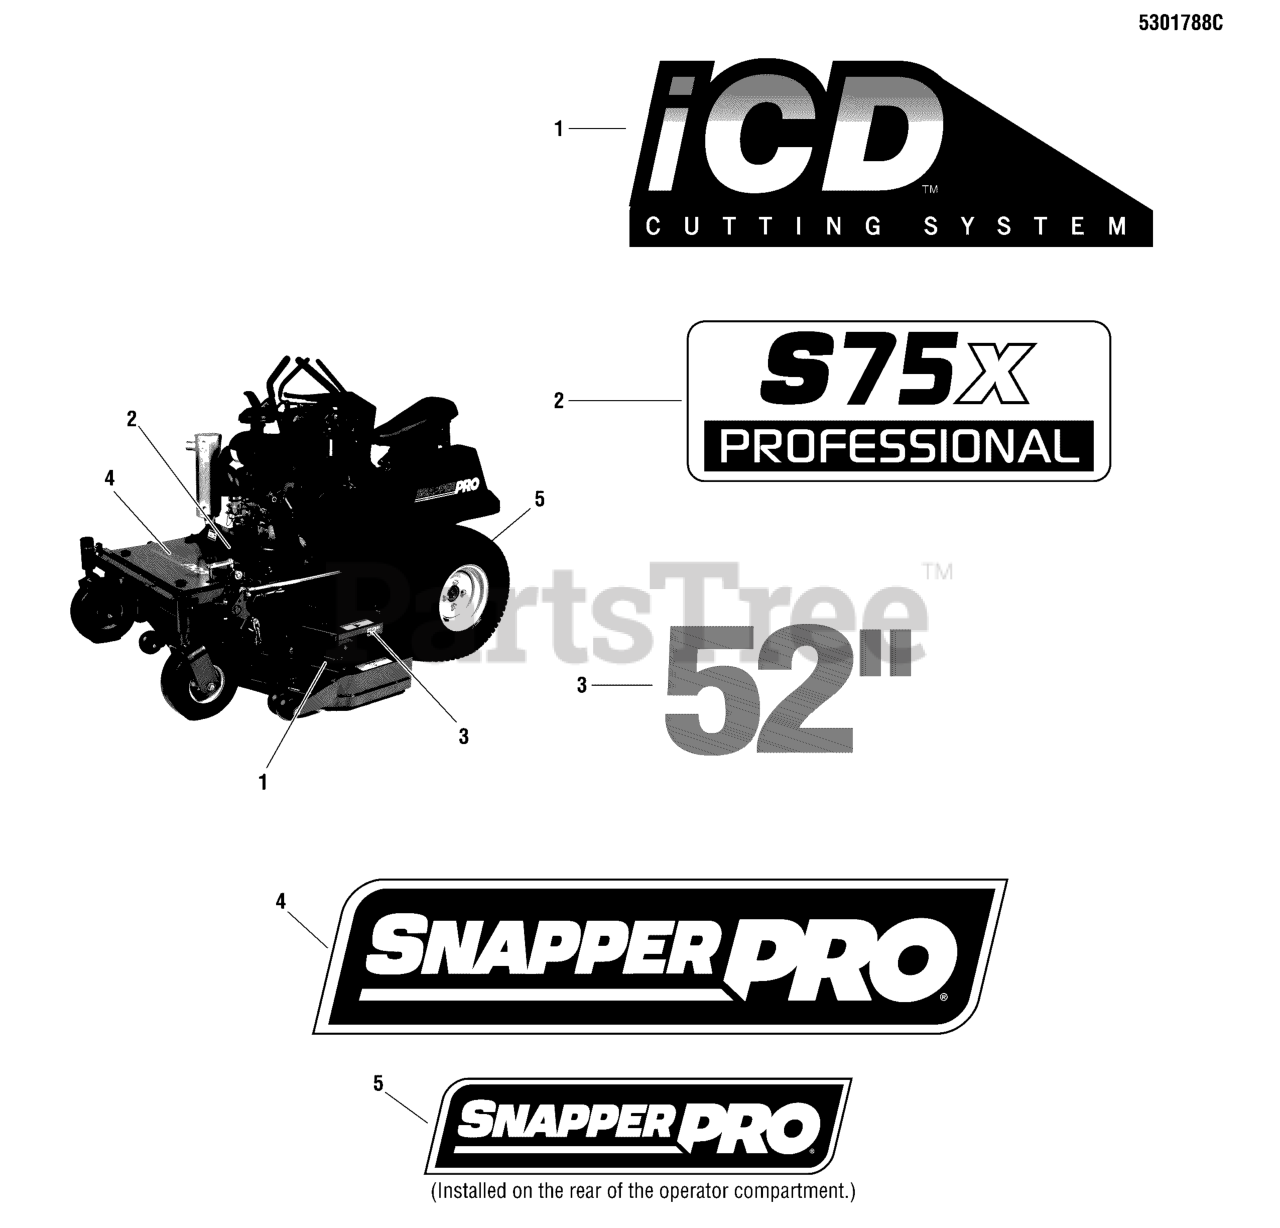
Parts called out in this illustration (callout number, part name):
1	DECAL, ICD CUTTING SYSTEM
2	DECAL, S75X (2014)
3	DECAL, 52
4	DECAL, SNAPPER PRO LOGO, LARGE
5	DECAL, SNAPPER PRO LOGO, MEDIUM
